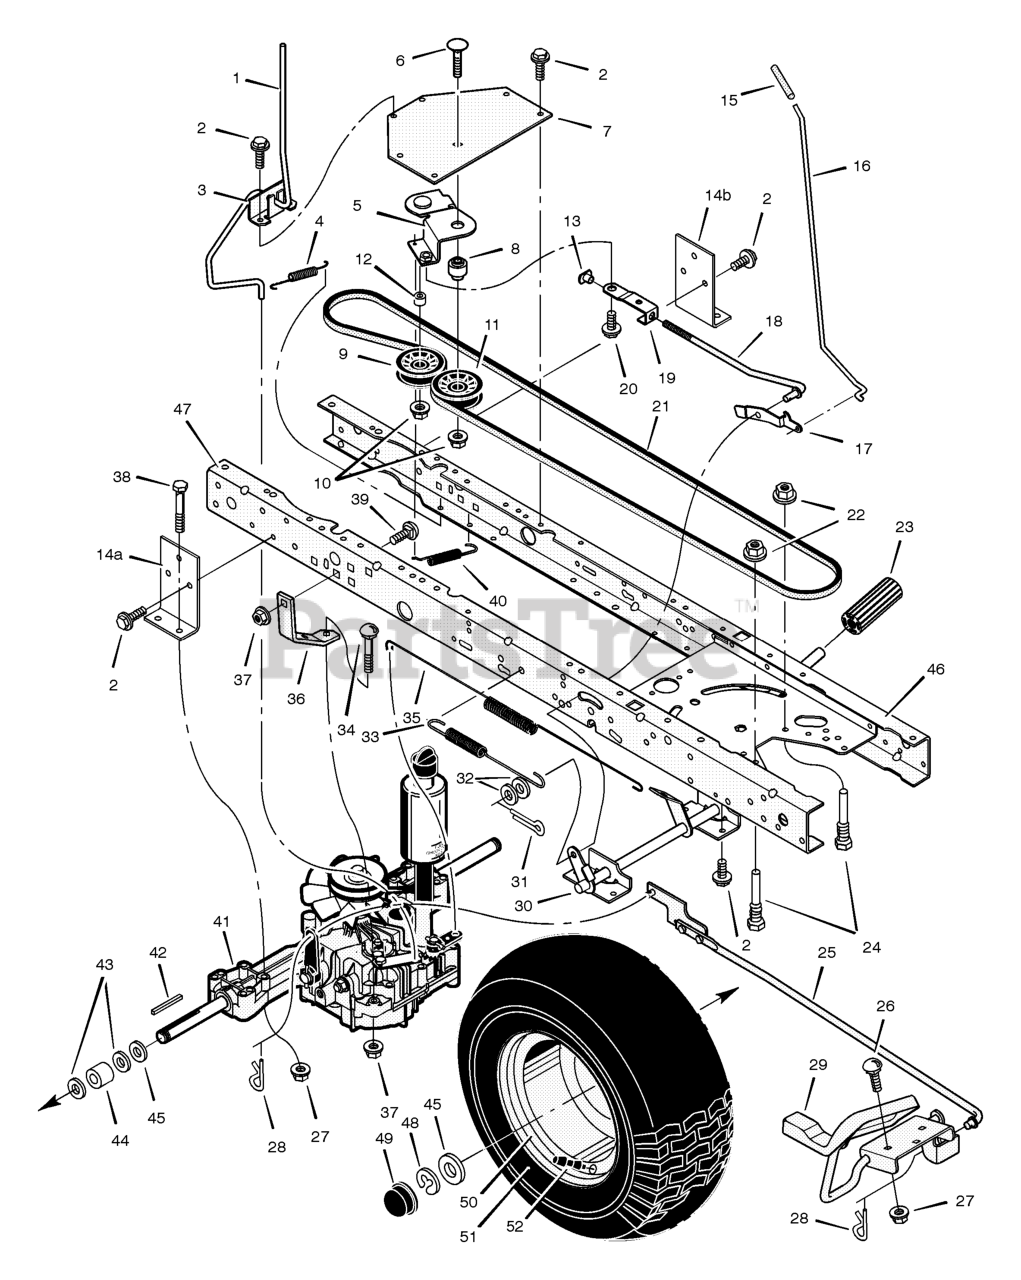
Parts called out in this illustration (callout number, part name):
1	Rod, Roll Release
3	Bracket, Disconnect
4	Spring, Extension
5	Assembly, Idler Arm
6	Bolt, Carriage
7	Bracket, Idler Pivot
8	Bushing, Pivot
9	Pulley, Idler
10	Nut, Flange
11	Pulley, Idler
13	Nut, Tee
14A	Bracket, Right Transaxle
14B	Bracket, Left Transaxle
16	Rod, Parking Brake
17	Latch, Parking Brake
18	Rod, Parking Brake
19	Link, Clutch
20	Bolt, Shoulder
21	Belt, Drive
22	Nut, Flange
23	Pedal
24	Guide, Belt
25	Assembly, Control Rod
26	Bolt, Carriage
27	Nut, Flange
28	Pin, Hair
29	Pedal, Speed Control
30	Assembly, Brake Pedal
31	Pin, Cotter
33	Spring, Extension
34	Bolt, Carriage
35	Spring, Brake
36	Strap, Torque
37	Locknut
38	Bolt
39	Bolt, Carriage
40	Spring, Clutch
41	Transmission *
42	Key, Square
46	Frame, Left
47	Frame, Right
49	Cap, Hub
50	Wheel & Tire Assembly
52	Stem, Valve
